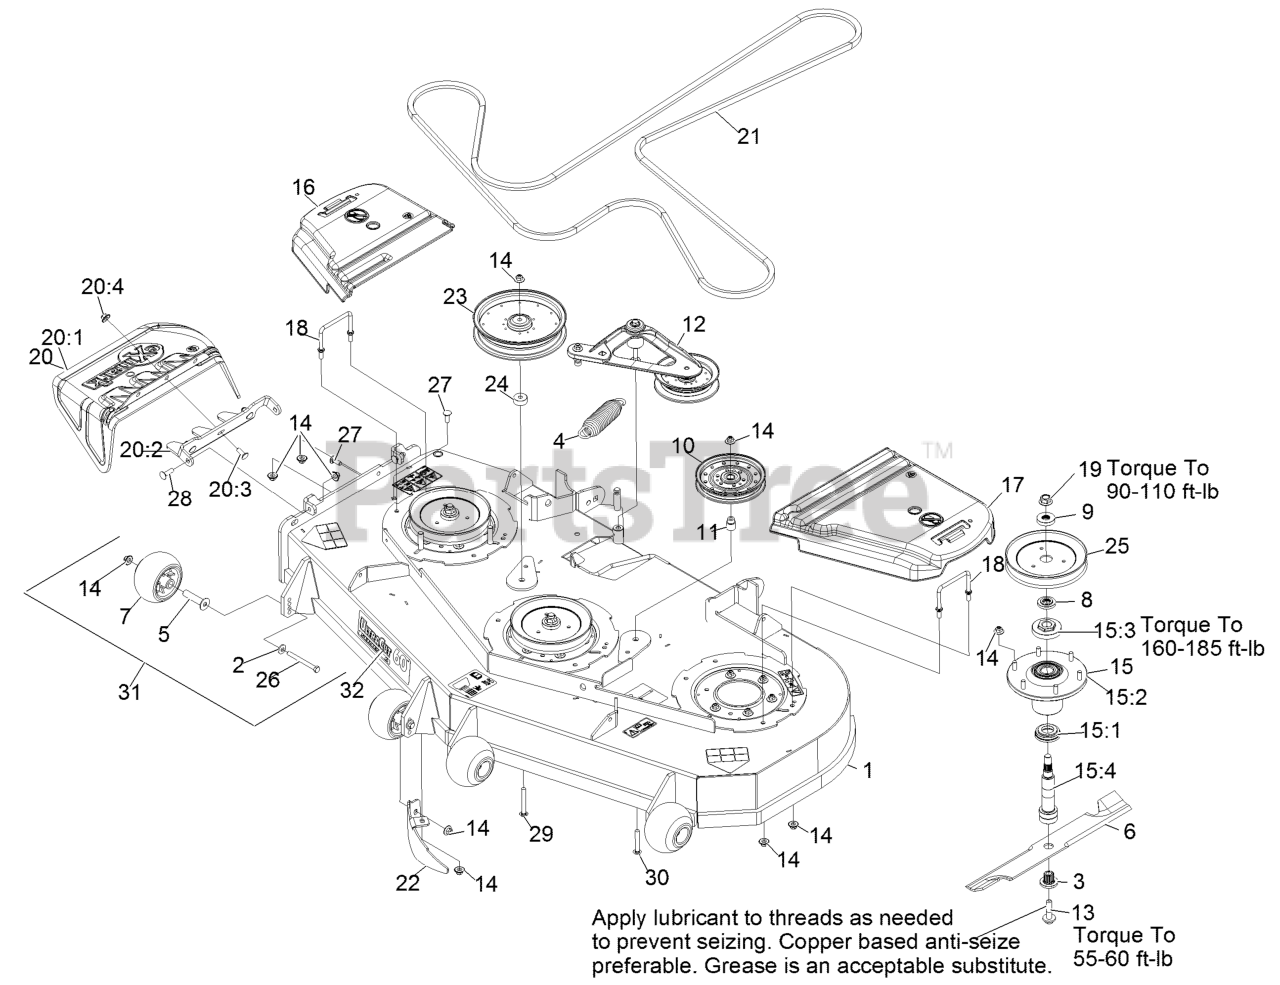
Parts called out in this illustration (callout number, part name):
1	DECK ASM,W/DECALS 60
2	WASHER-BELLEVILLE
3	BUSHING,SPLINED
4	SPRING-EXTENSION
5	AXLE, ROLLER
6	Blade-Extreme 2, 20.50"
7	ROLLER-SCALP, ANTI
8	SPACER,SPLINED STEPPED
9	SPACER,SPLINED
11	BUSHING-IDLER
12	DECK IDLER ASM
13	SCREW,SEMS 1/2-20 X 2.19
14	Nut-Nyloc 3/8-16 Flg
15	ASM,SPINDLE HOUSING
15:1	GUARD,BOTTOM
15:2	ASM,CUTTER HOUSING
15:3	NUT, SPINDLE 7/8-14
15:4	SPINDLE,DOUBLE SPLINE
16	COVER-BELT, RH
17	COVER-BELT, LH
18	WIREFORM-COVER
19	NUT-FLANGE, CENTERLOCK
20	ASM,DISCHARGE CHUTE
20:1	CHUTE,DISCHARGE
20:2	BRACKET,DISCHARGE CHUTE
20:3	SCREW-CARR
20:4	Nut-Nyloc 3/8-16 Flg
21	BELT,V-5V-198.75
22	DOGLEG - LZ60
23	PULLEY-IDLER
24	SPACER-IDLER
25	SHEAVE,BLADE DRIVE 7.25
26	SCREW-HH 3/8-16 X 3 3/4 GR 8
27	SCREW-CARR
28	Bolt-Carriage 3/8-16 X 1 1/4
29	SCREW-CARR
30	SCREW-CARR
31	KIT, ANTI-SCALP ROLLER
32	DECAL,ULTRACUT 60 SERIES
